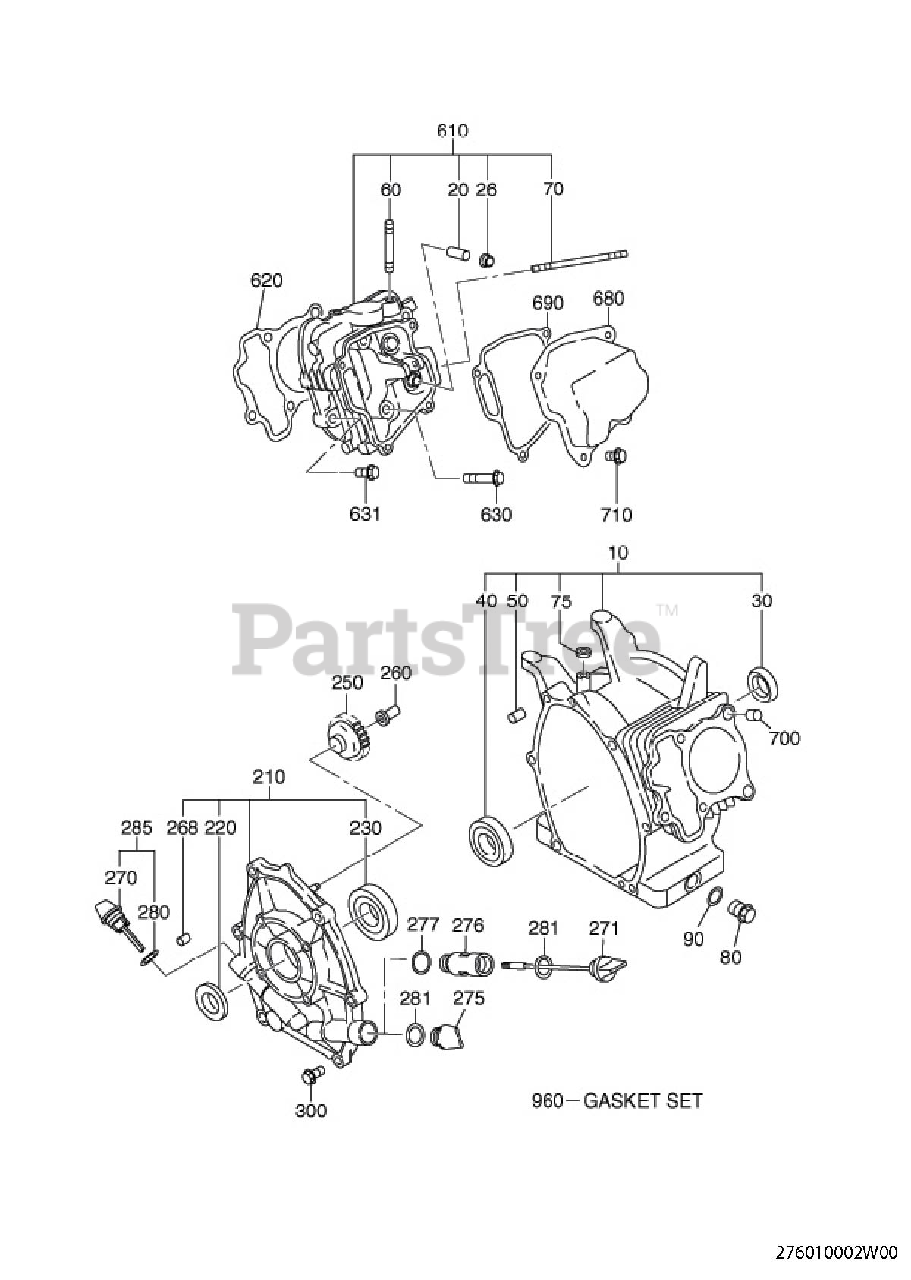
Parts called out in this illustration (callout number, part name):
10	CRANK CASE CP
20	VALVE GUIDE
26	STEM SEAL
30	OIL SEAL
40	BALL BEARING
50	PIPE KNOCK
60	STUD
70	STUD
75	OIL SEAL
80	PLUG
90	GASKET
210	MAIN BEARING COVER C
220	OIL SEAL
230	BALL BEARING
250	GOVERNOR GEAR CP
260	GOVERNOR SLEEVE
270	OIL GAUGE
280	GASKET
300	FLANGE BOLT
610	CYLINDER HEAD CP
620	GASKET (HEAD)
630	FLANGE BOLT
631	FLANGE BOLT
680	ROCKER COVER CP
690	GASKET(ROCKER COVER)
700	PIPE KNOCK
710	FLANGE BOLT
960	GASKET SET
